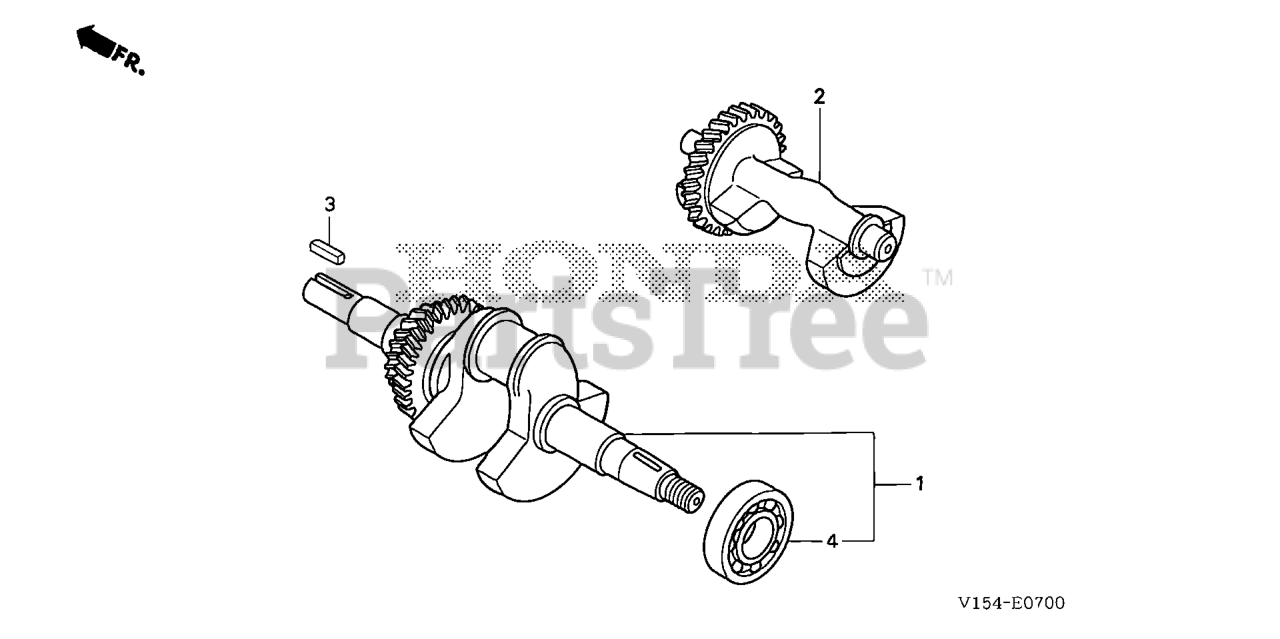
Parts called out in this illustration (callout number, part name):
1	CRANKSHAFT
2	WEIGHT, BALANCER
4	BEARING, RADIAL BALL (6207SH)
